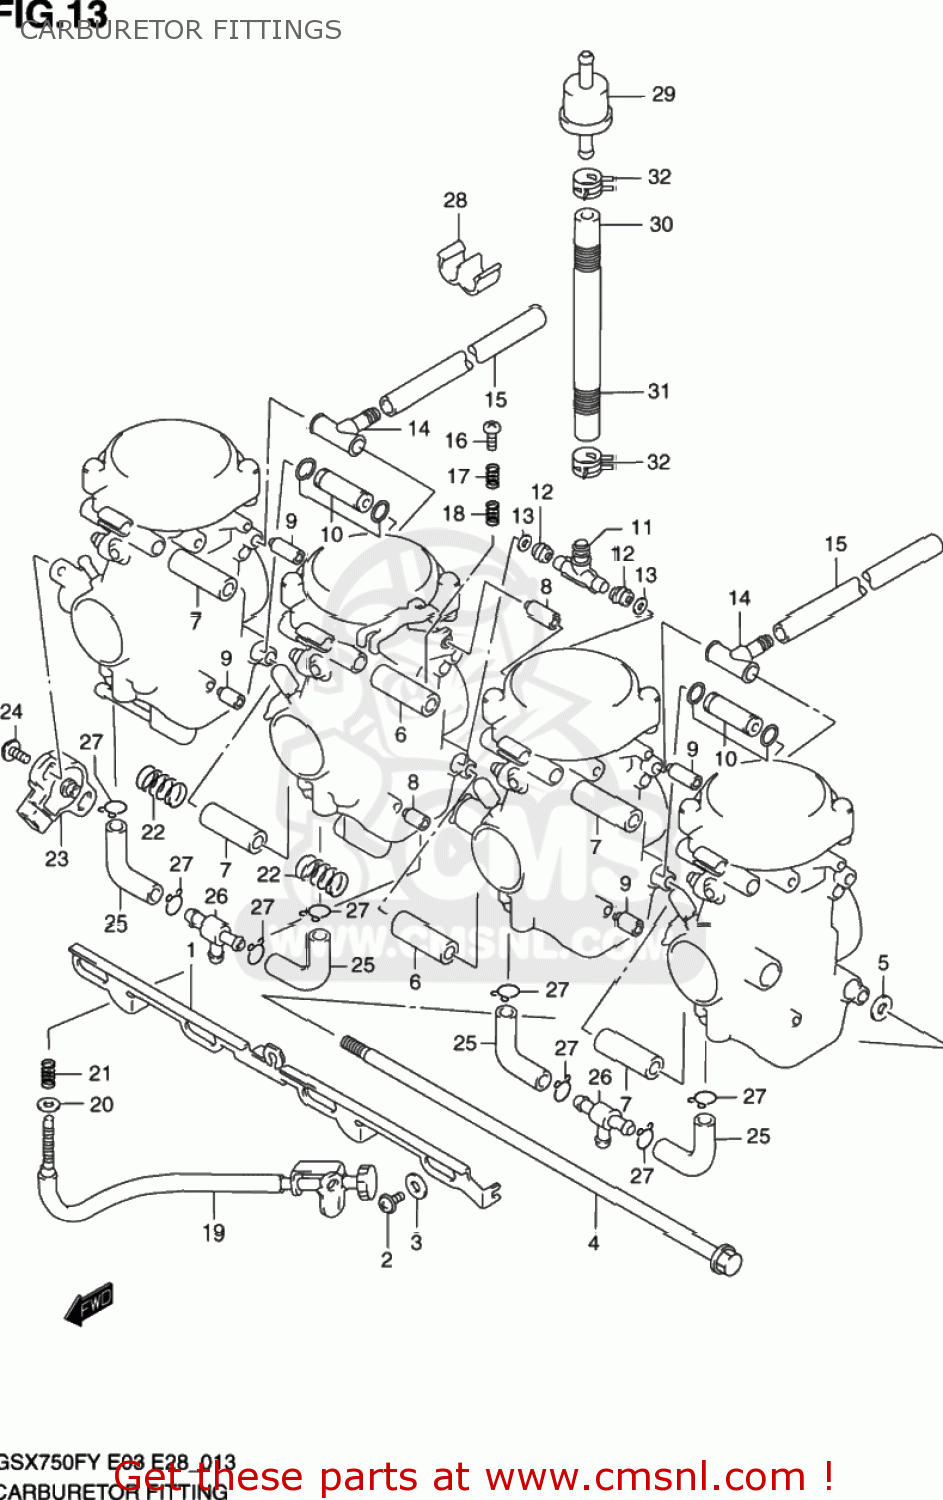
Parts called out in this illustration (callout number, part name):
1	LEVER
2	SCREW
3	PACKING
4	BOLT
5	WASHER
6	PIPE
7	PIPE
8	ROD
9	ROD
10	PIPE
11	NIPPLE
12	SEAL
13	WASHER,DRAIN PLUG
14	HOSE
15	HOSE
16	SCREW
17	SPRING
18	SPRING,THROTTLE SCREW
19	SCREW,ADJUST
20	WASHER,STARTER SHAFT
21	SPRING
22	SPRING
23	SENSOR ASSY,THROTTLE
24	SCREW,SENSOR
25	HOSE
26	NIPPLE
27	CLIP
28	CLIP
29	STRAINER COMP,FUEL
30	HOSE(7X12X600)
31	SPRING
32	CLIP
